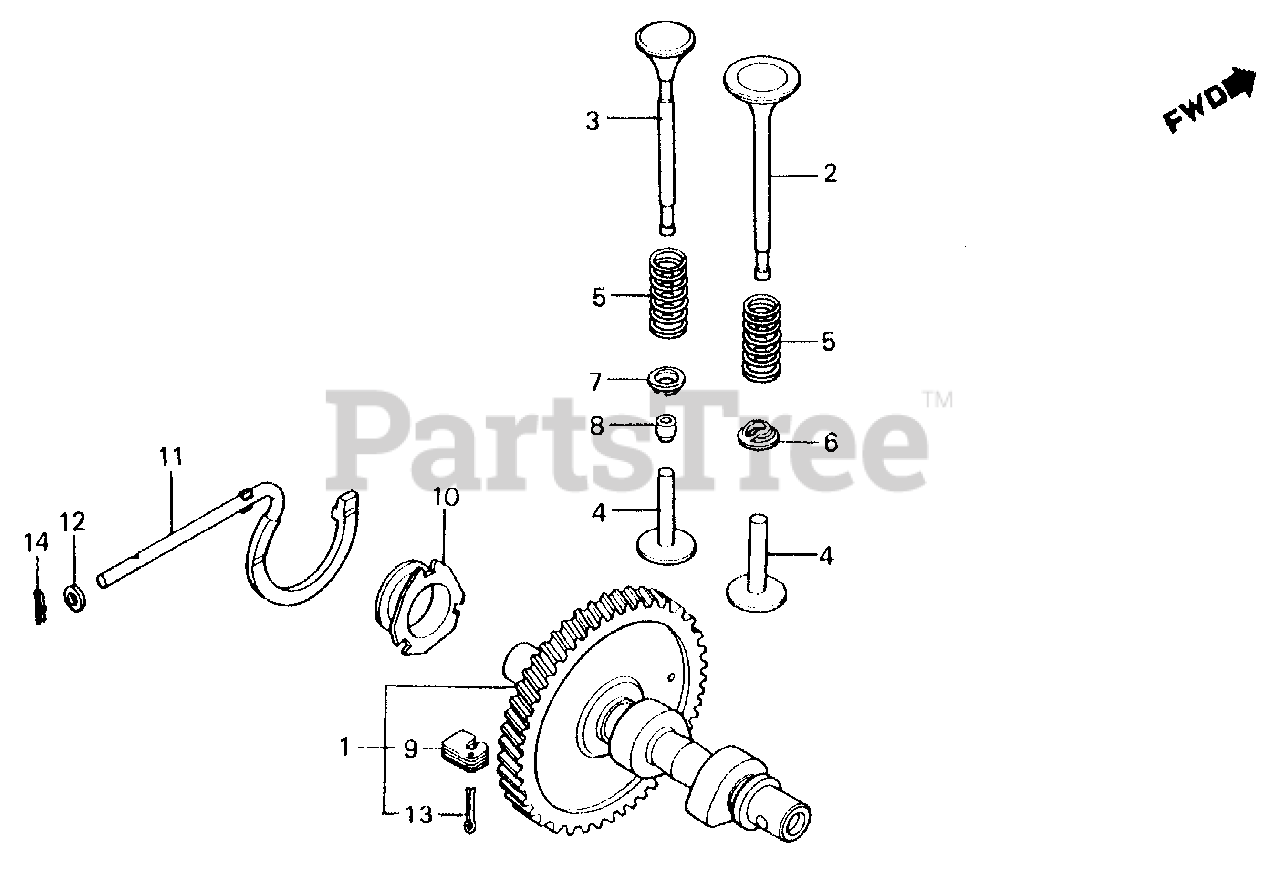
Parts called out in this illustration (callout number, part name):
2	VALVE, IN.
3	VALVE, EX.
4	LIFTER, VALVE (45.89MM)
4	LIFTER, VALVE (46.04MM)
4	LIFTER, VALVE (46.19MM)
4	LIFTER, VALVE (46.34MM)
5	SPRING, VALVE
6	RETAINER, VALVE SPRING
7	RETAINER, VALVE SPRING
8	ROTATOR, EX. VALVE
9	WEIGHT, GOVERNOR (NOT AVAILABLE)
10	SLIDER, GOVERNOR
11	SHAFT, GOVERNOR ARM
12	WASHER, PLAIN (6MM)
13	PIN, COTTER (3.0X15)
14	PIN, LOCK (10MM)
